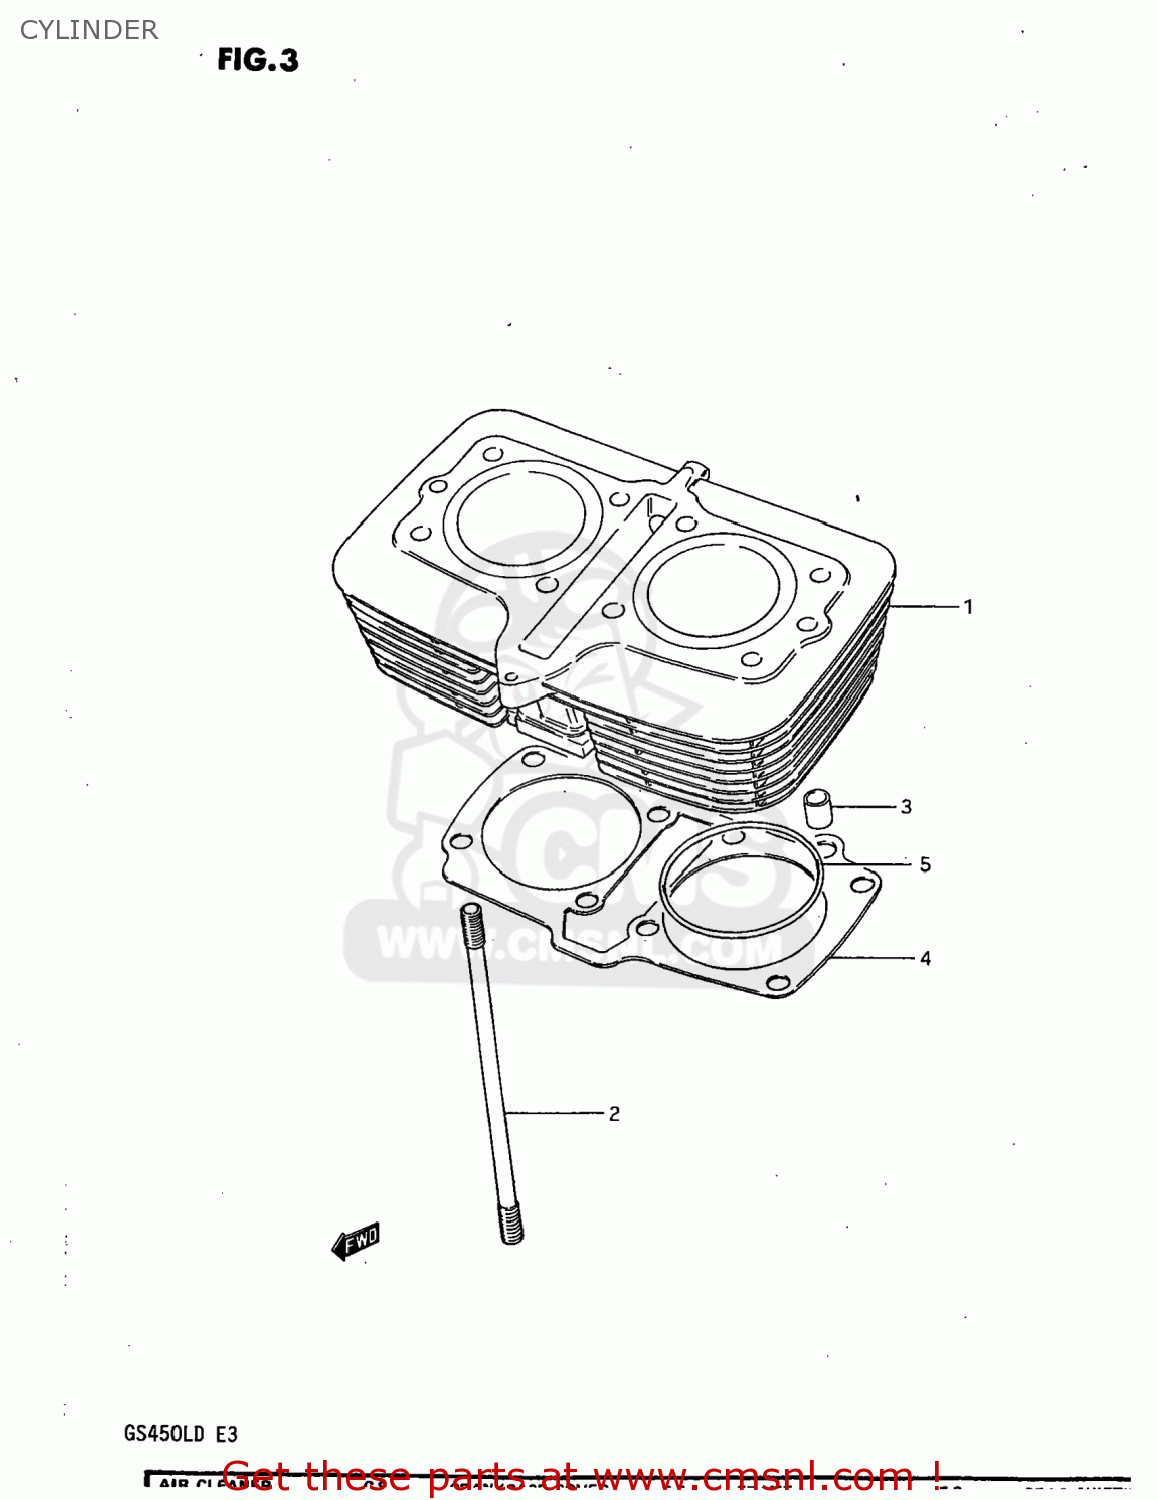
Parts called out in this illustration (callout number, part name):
1	CYLINDER
2	STUD
3	PIN
4	GASKET,CYLINDER (MCA)
5	O RING(D:2,ID:74)
